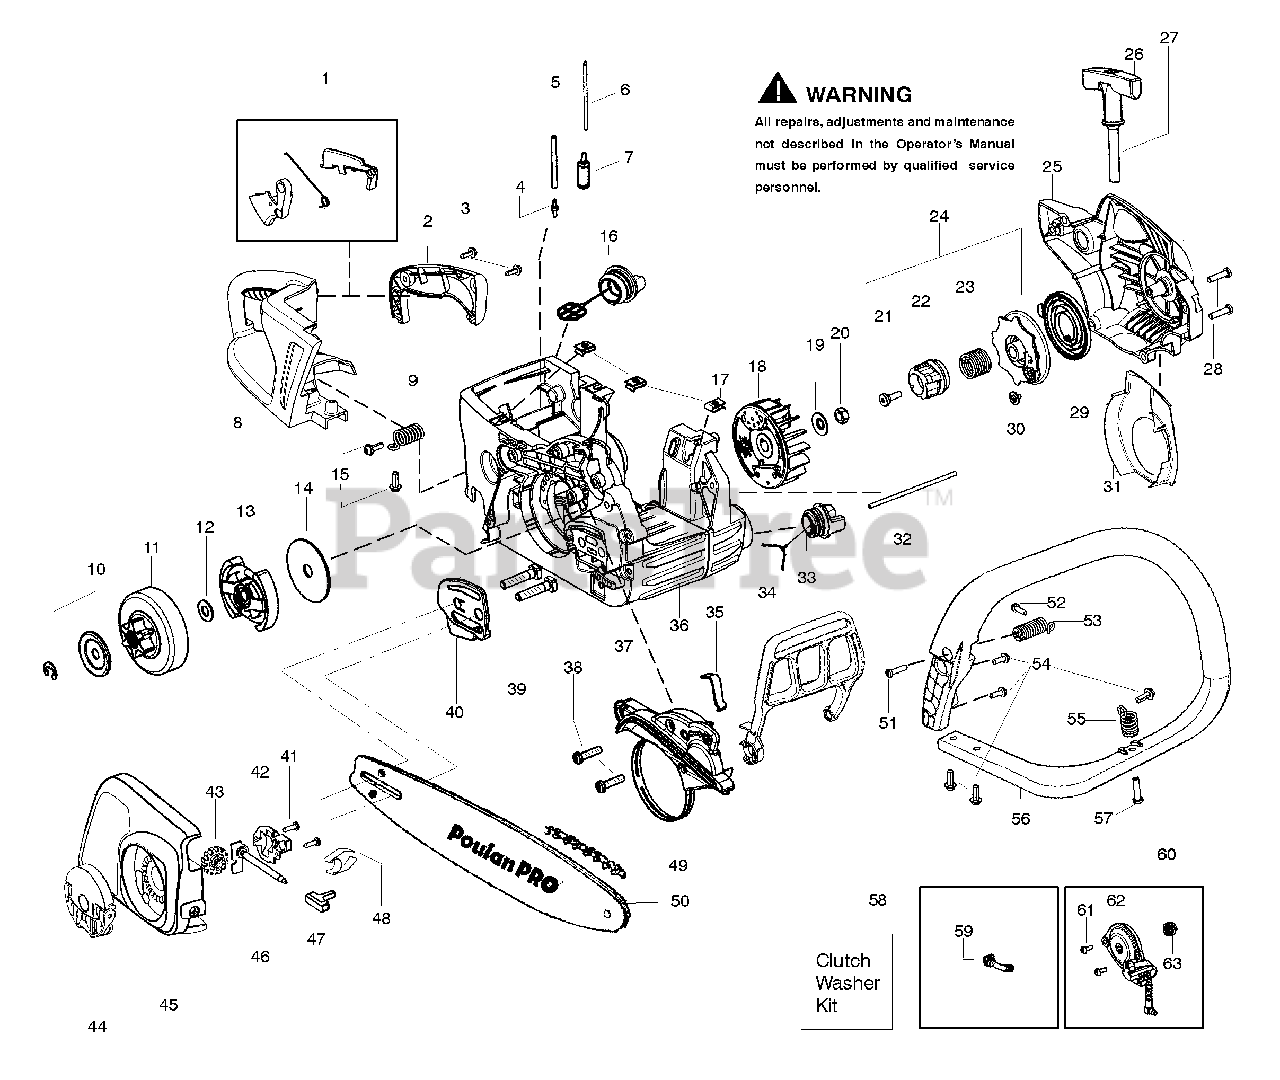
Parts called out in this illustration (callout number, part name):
1	Kit-Trigger/Lockout
2	Cover-Handle
4	Fitting-Fuel line
5	Kit-Fuel Line
6	Kit-Fuel Line
7	Assy-Fuel Pick Up
8	Handle-Rear
9	Spring-Rear Isolator
10	Kit-Clutch Washer
11	Assy-Clutch Drum 3/8"
12	Kit-Clutch Washer
13	Assy-Clutch
14	Washer-Large Clutch
16	Assy-Fuel Cap w/ret
17	Nut-"U" type speed
18	Assy-Flywheel
19	Washer-Flywheel
20	Nut-Flywheel
21	Screw-Shoulder
22	Starter Hub-EPS
23	Spring-EPS
24	Kit- EPS Starter Pulley
25	Housing-Fan
26	Handle-Starter
27	Kit-Rope
29	Spring-Starter
32	Assy-Oil Vent
33	Assy-Oil Cap w/ret.
34	Handguard
35	Spring-Handguard
36	Assy-Chassis
37	Kit-Chainbrake
39	Bolt-Bar
40	Plate-Bar
42	Cover-Gearbox
43	Wheel-Bar Adjust
44	Assy-Knob
45	Clutch Cover
46	Assy-Adjust Screw
47	Pin-Bar Adjust
48	Spring - Clip
49	Accy-18" Chain
50	Bar - 18"
53	Assy-Rear Iso. Spring
55	Assy-Front Iso. Spring
56	Handle-Front
58	Kit-Clutch Washer
59	Assy-Oil Pick Up
60	Kit-Oil Pump
62	Assy-Oil Pump
63	Gear-Worm
